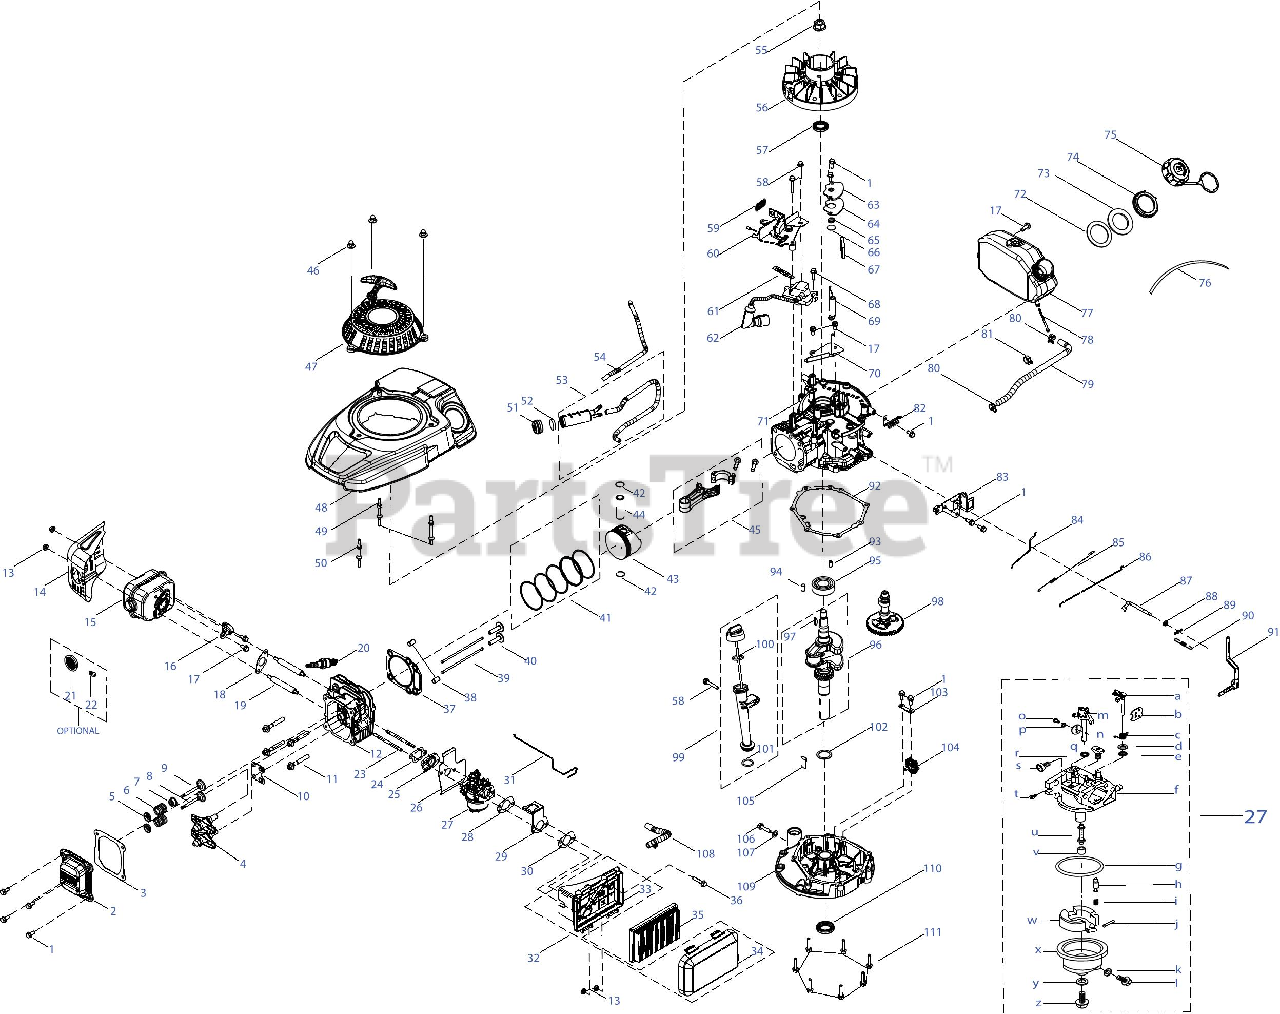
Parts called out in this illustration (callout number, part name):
1	Bolt M6x14
2	Valve Cover
3	Valve Cover Gasket
4	Rocker Arm Assembly
5	Valve Spring Retainer
6	Valve Spring
7	Intake Valve Seal
8	Exhaust Valve
9	Intake Valve
10	Push Rod Guide
11	Bolt M8x54 Cylinder Head
12	Cylinder Head
13	Nut M6X10
14	Muffler Shield
15	Muffler Assembly
16	Choke Thermal Control
17	Bolt M6x12
18	Muffler Gasket
19	Muffler Stud M6x95
20	Spark Plug/F5RTC
21	Spark Arrestor
22	Spark Arrestor Screw
23	Carb Stud M6x87
24	Carburetor Insulator Gasket
25	Carburetor Insulator
26	Carburetor Gasket
27	Carburetor Assembly
28	Air Filter Bracket Gasket
29	Choke Thermal Control Bracket
30	Air Filter Base Gasket
31	Temp Control Linkage
32	Air Filter Assembly
33	Air Filter Base
34	Air Filter Cover
35	Air Filter Element, Paper
36	Bolt M6x30
37	Cylinder Head Gasket
38	Cylinder Head Dowel Pin 10x16
39	Push Rod
40	Tappet
41	Piston Ring Set
42	Piston Pin Snap Ring
43	Piston
44	Piston Pin
45	Connecting Rod Assembly
46	Starter Acorn Nut
47	Starter Recoil Assembly
48	Engine Shroud Assembly
49	Shroud Stud M6x78.5
50	Shroud Stud M6x74
51	Carbon Canister Filter Cap
52	Carbon Canister Filter
53	Carbon Canister Assembly
54	Carbon Canister Purge Hose
55	Flywheel Nut M14
56	Flywheel
57	Upper Crankshaft Seal
58	Bolt M6x35
59	Brake Spring
60	Brake Assembly
61	Flexible Clamp
62	Ignition Coil Assembly
63	Breather Cover Plate
64	Breather Gasket
65	Breather Valve Spring
66	Breather Valve
67	Breather Screen
68	Bolt M6x20
69	Air Vane
70	Air Vane Bracket
71	Crankcase
72	Fuel Tank Lower Grommet
73	Fuel Tank Upper Grommet
74	Fuel Tank Nut
75	Fuel Cap Assembly
76	Plastic Tie 150Mm
77	Fuel Tank
78	Fuel Filter
79	Fuel Hose
80	Fuel Hose Clamp
81	Plastic Support Clamp, Hose
82	Flexible Clamp
83	Component Bracket
84	Choke Linkage
85	Throttle Linkage Spring
86	Throttle Linkage
87	Governor Arm Shaft
88	Governor Seal
89	Governor Arm Shaft Cotter Pin
90	Governor Spring
91	Governor Arm Assembly
92	Crankcase Cover Gasket
93	Crankcase Cover Dowel Pin 7x14
94	Crankcase Cover Dowel Pin 9x14
95	Main Bearing
96	Crankshaft Assembly
97	Flywheel Key
98	Camshaft Assembly
99	Dipstick Assembly
100	Dipstick / Oil Fill Tube O-Ring
101	Dipstick / Oil Fill Tube O-Ring
102	Crankshaft Thrust Washer
103	Governor Gear Mounting Plate
104	Governor Gear/Shaft Assembly
105	Oil Return Seal
106	Oil Drain Plug
107	Oil Drain Plug Washer
108	Breather Hose Assembly
109	Crankcase Cover
110	Lower Crankshaft Seal
111	Bolt M6x28
Z	Fuel Bowl Mounting Bolt
